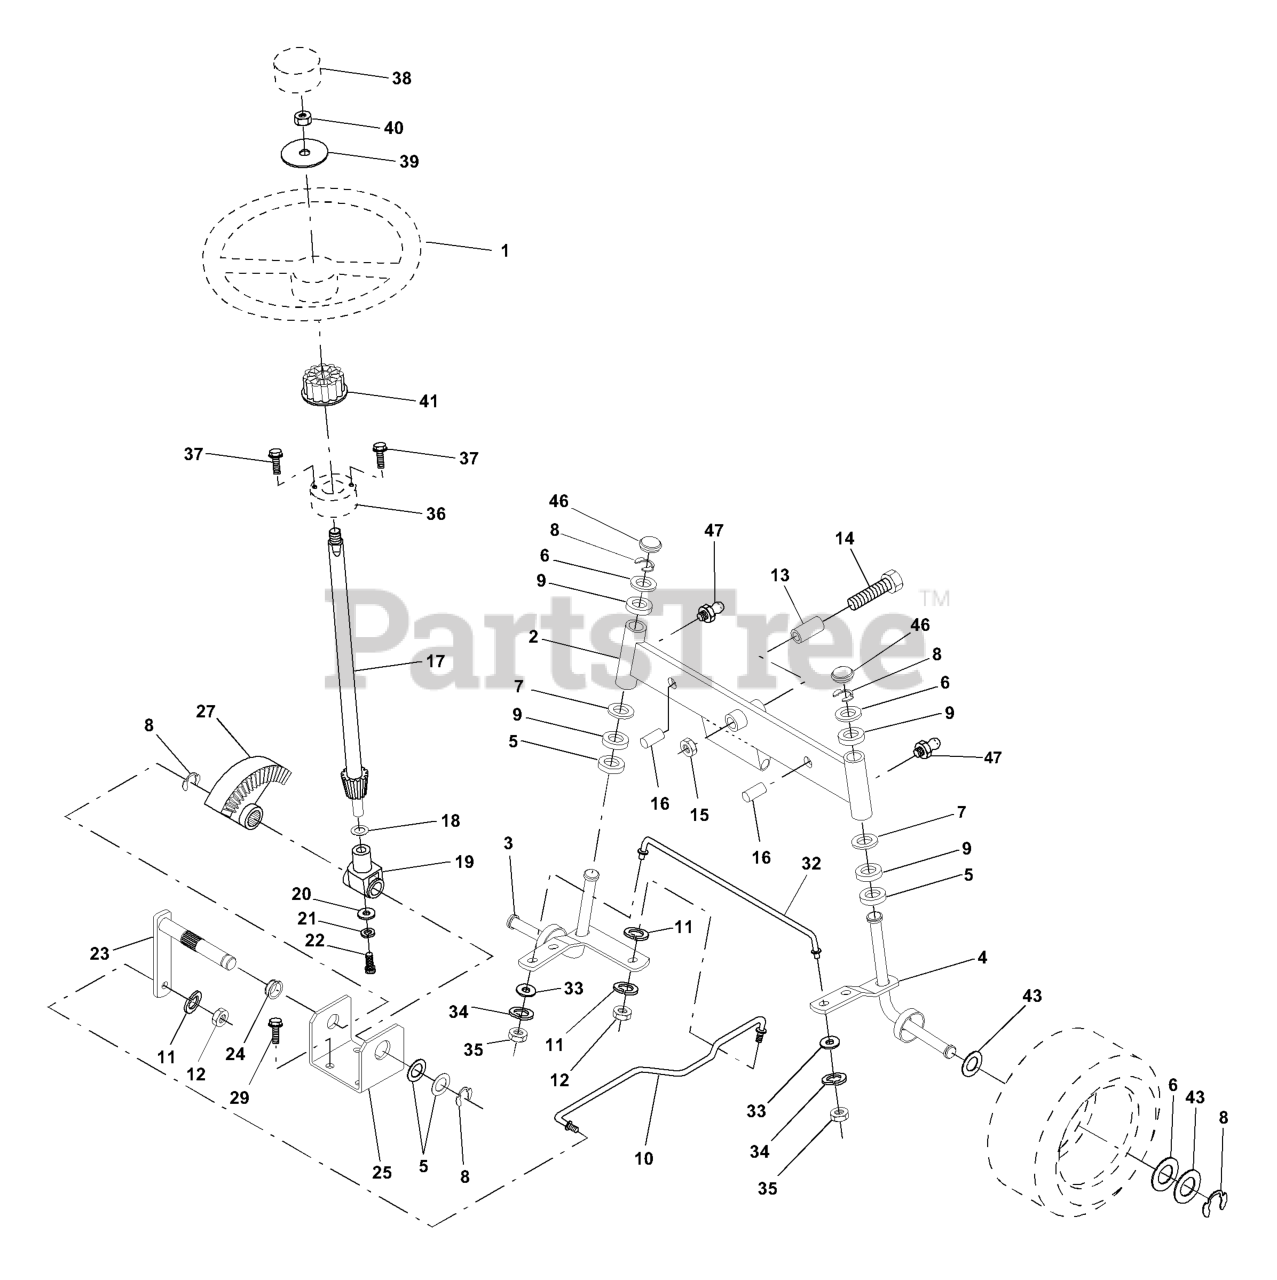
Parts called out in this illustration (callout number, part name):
1	STEERING WHEEL
3	SPINDLE LH
4	SPINDLE RH
5	THRUST WASHER
9	BRNG T
10	LINK.DRAG.SOL.BALL JT.20.064
11	WASHER, LOCK 3/8
12	NUT
13	BEARING
14	Bolt Hex 5/8-11 Unc X 3-1/2
15	NUT-LOC,FLANGE LT
17	SHAFT STR
18	THRUST WASHER
19	SHAFT,SUPPORT
20	WASHER
21	LOCKWASHER
22	SCREW,SPECIAL
23	SHAFT PITMAN
24	NYLINER T (7283A)
25	BRKT,STEERING
27	GEAR.SECTOR
29	SCREW
32	TIE ROD
33	WASHER M
34	WASHER.LOCK.HVY.HLCL.SPR.5/16
35	LOCKNUT
36	BUSHING LT
37	SCREW LT
38	INSERT,STR WHEEL
40	NUT.HEX.1/2-20
41	ADAPTER LT
46	CAP.SPINDLE.BLACK
47	ZERK M
